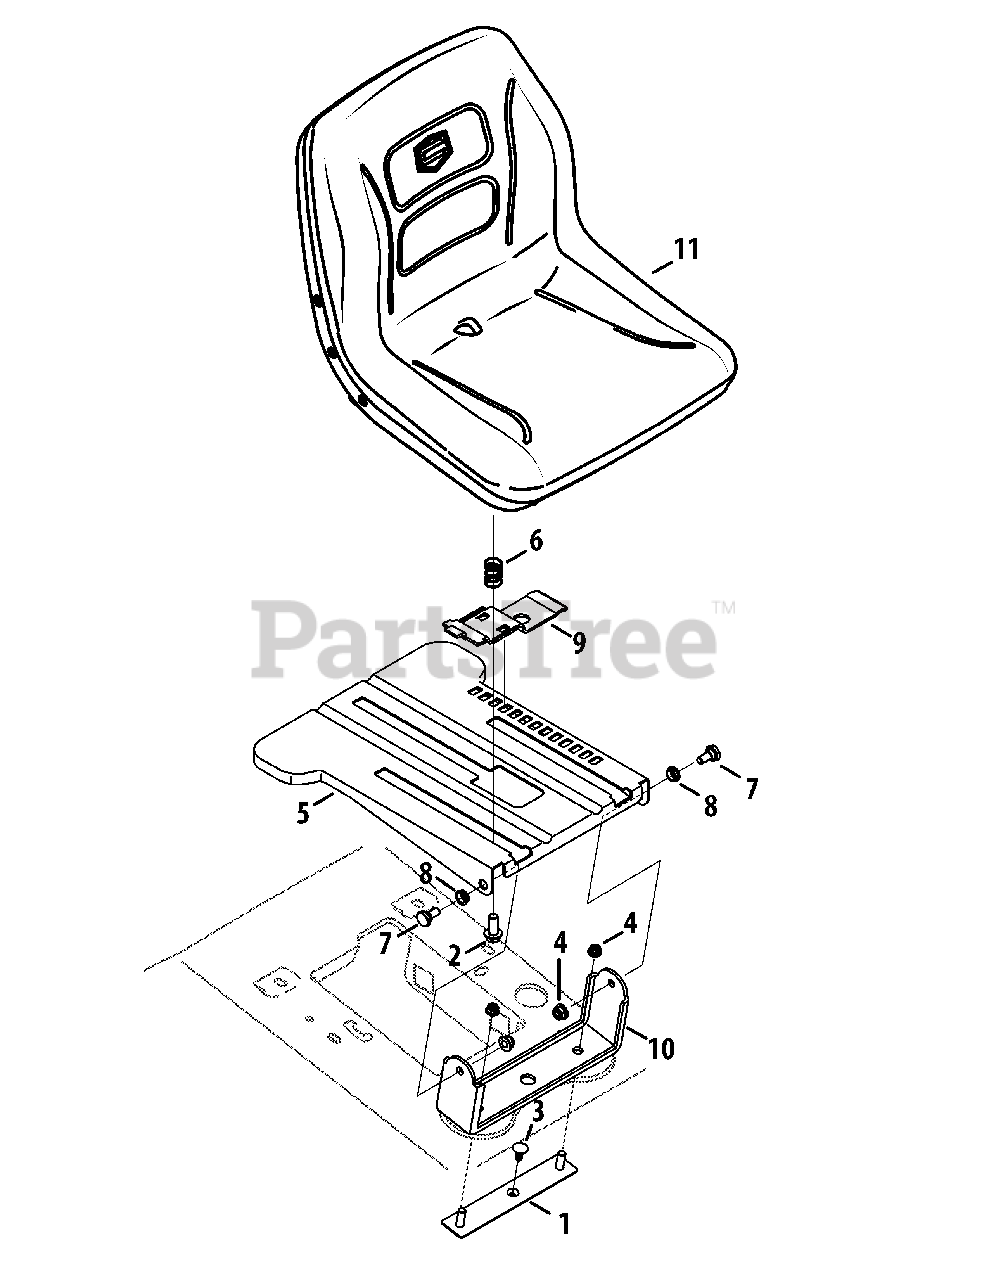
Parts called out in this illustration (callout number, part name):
1	Seat Pivot Plate Assembly
2	Hex Flange Screw, 3/8/16, .875, Gr5
3	Ratchet Clip
4	Nut, Flange Lock, 5/16-18, Grf
5	Bracket, Mounting, Seat
6	Compression Spring, .68 x 1.065 x .055
7	Shoulder Screw, .435 x .178, 5/16 x .56
8	Flange Bearing, .4385 ID
9	Seat Lever
10	Pivot Bracket, Tall
11	Seat
